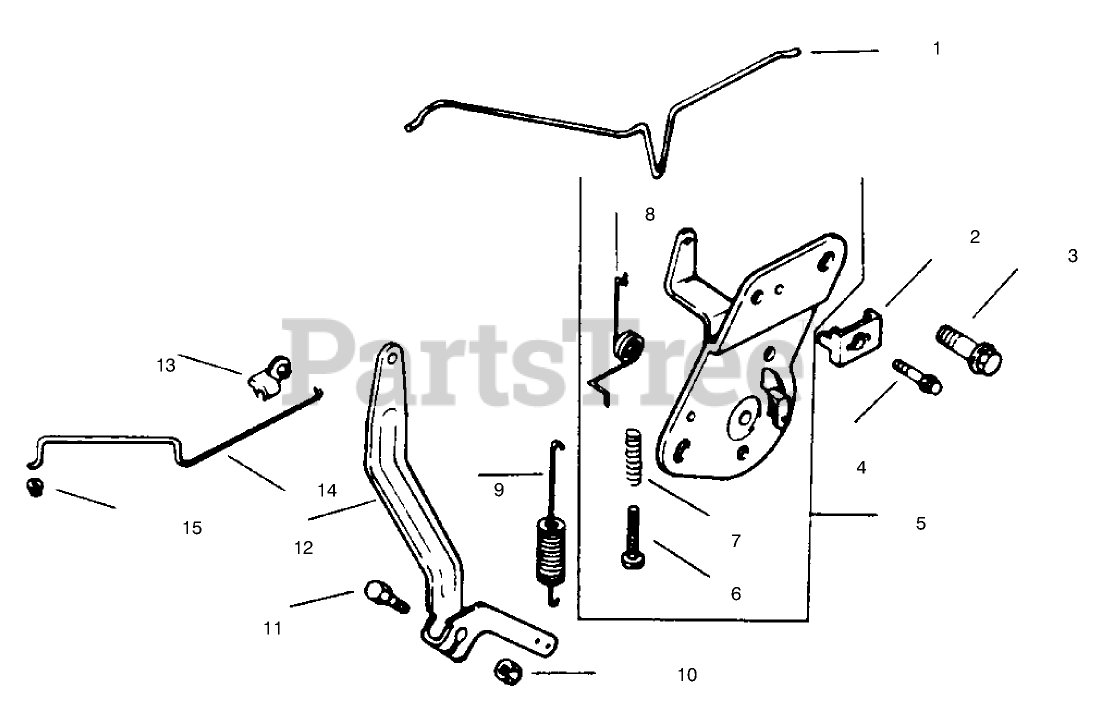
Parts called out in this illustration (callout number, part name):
1	Linkage Choke
2	Clamp
3	Screw
4	Screw
5	Control-Speed
6	Screw
7	Spring
8	Spring Choke
9	Spring-Governor
10	Nut
11	Screw
12	Lever-Governor
13	Bushing-Linkage
14	Linkage-Throttle
15	Bushing-Linkage
